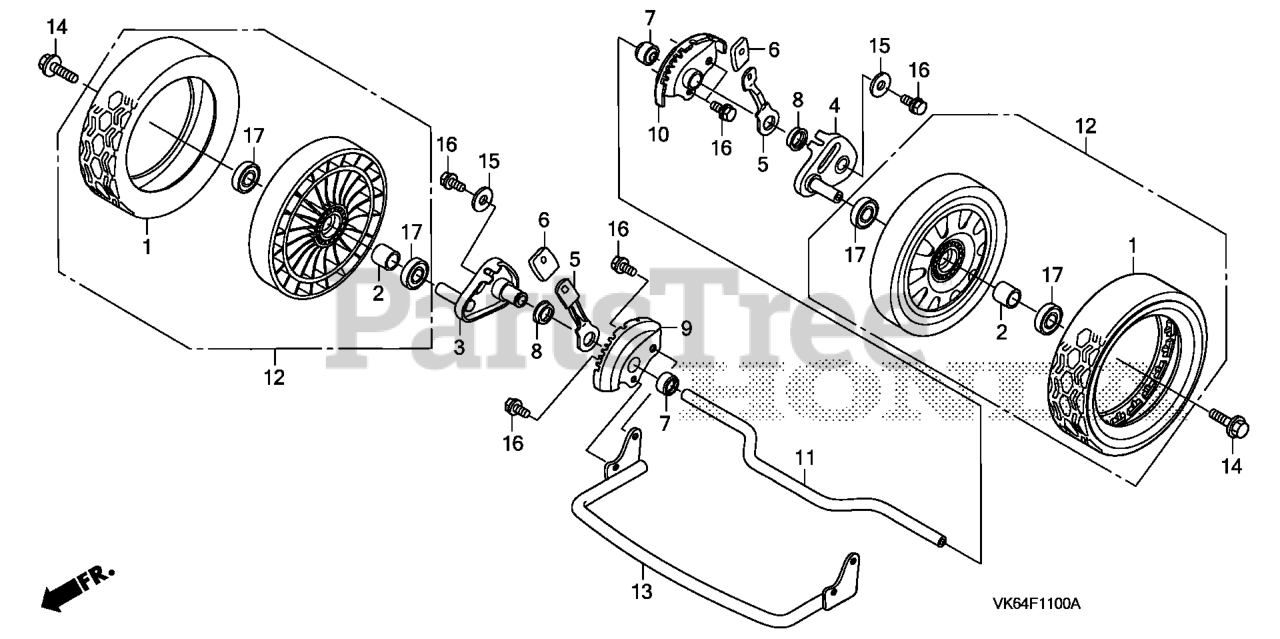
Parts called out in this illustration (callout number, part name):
1	TIRE (9 INCH)
2	COLLAR, WHEEL
3	ARM, R. FR. ADJUSTING
4	ARM, L. FR. ADJUSTING
5	PLATE, FR. ADJUSTER
6	GRIP, ADJUSTER
6	GRIP, ADJUSTER *NH105* (MAT BLACK)
7	DUST SEAL A
8	DUST SEAL, R.
9	PANEL, R. FR. ADJUSTER
10	PANEL, L. FR. ADJUSTER
11	SHAFT, FR. AXLE
12	WHEEL ASSY., FR. *NH462R* (VINTAGE GRAY SOLID)
13	GUARD, FR.
14	BOLT, WHEEL
15	WASHER, RR. ENGINE MOUNTING
16	BOLT, FLANGE (8X16) Use from Engine SN 1000016.
17	BEARING, RADIAL BALL (6002UU)
